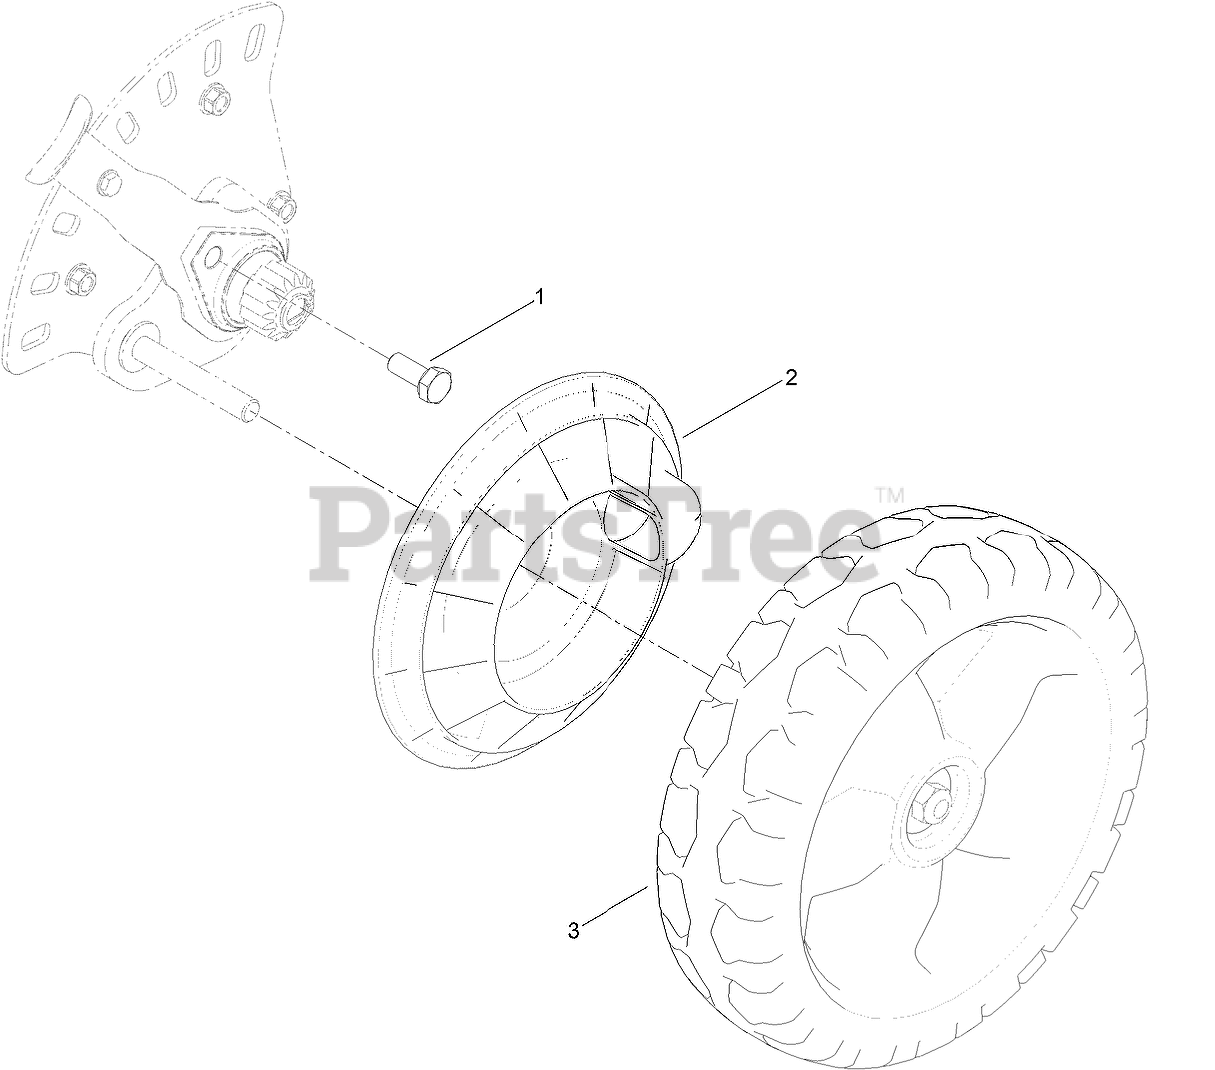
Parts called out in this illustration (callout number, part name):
1	SCREW-HH
2	COVER-WHEEL
3	9-INCH WHEEL ASM
